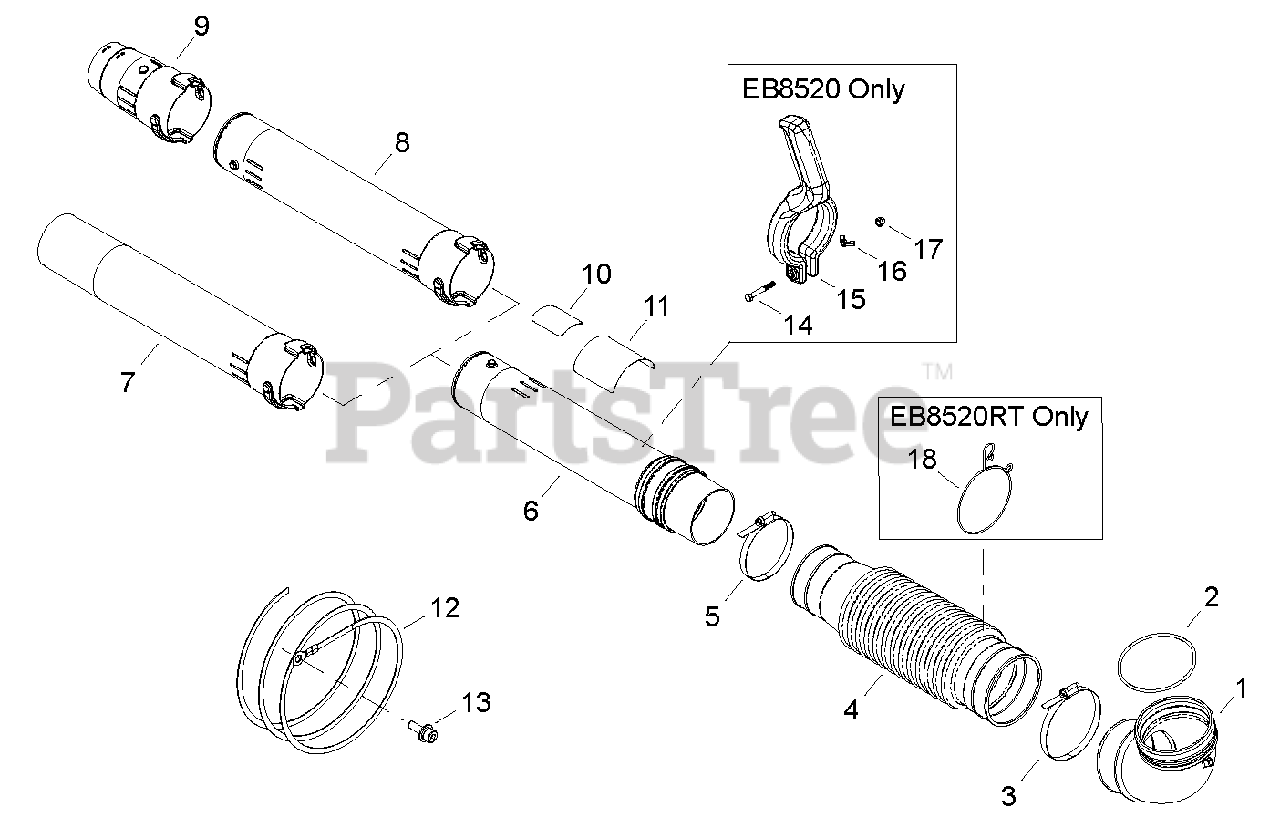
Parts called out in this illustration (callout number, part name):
1	TUBE, BLOWER - ELBOW
2	O-RING
3	CLAMP
4	TUBE, BLOWER - FLEXIBLE
5	CLAMP
6	TUBE, BLOWER - SWIVEL
7	TUBE, BLOWER - NOZZLE
8	TUBE, BLOWER - STRAIGHT
9	TUBE, BLOWER - NOZZLE
10	LABEL, CAUTION - CLOGGED INLET
11	LABEL, C4
12	WIRE, STATIC DISCHARGE 1050 MM
13	BOLT M5×16
14	BOLT M6×60
15	HANDLE
16	NUT, WING M7
17	NUT M6
